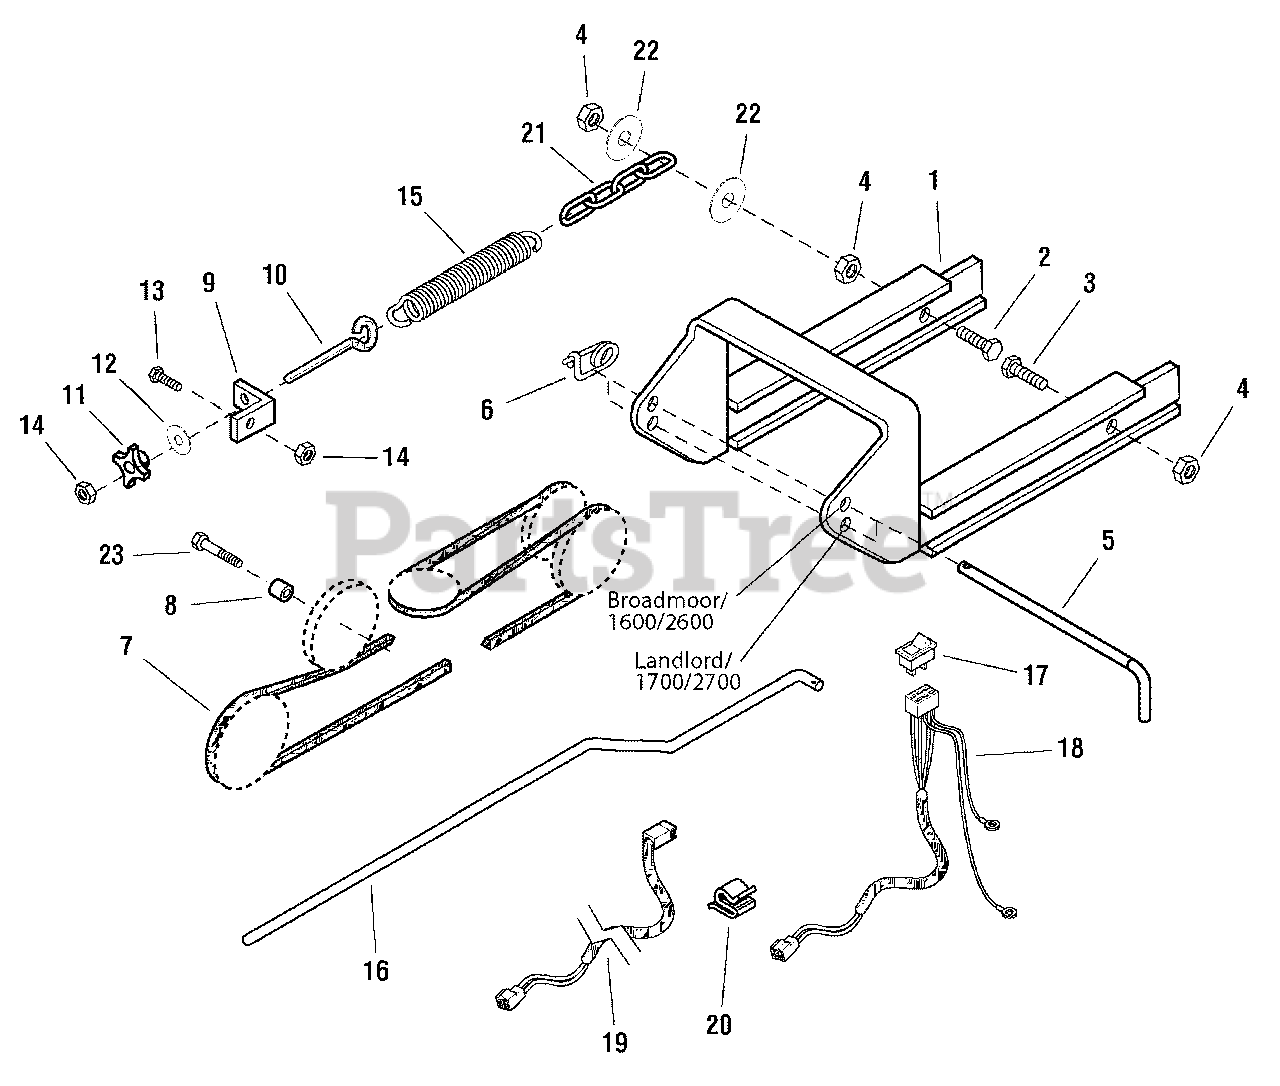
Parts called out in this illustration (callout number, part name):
1	HITCH ADAPTER
2	CAPSCREW, 3/8-16 x 2
3	CAPSCREW, 3/8-16 x 1-1/4
4	LOCKNUT, Flange, 3/8-16
5	ROD, 5/8 x 13
6	SAFETY CLIP
7	V-BELT
9	BRACKET, L
10	EYEBOLT, 5/16-18 x 5
12	WASHER, 5/16
13	CAPSCREW, 5/16-18 x 1-1/4
14	LOCKNUT, 5/16-18
15	SPRING, Extension
17	SWITCH, Rotator
18	HARNESS, Spout Rotator Adapter
19	WIRE HARNESS, 50"
21	CHAIN, 4-Link
22	WASHER, Plain
23	CAPSCREW, 3/8-16 x 2-1/4
